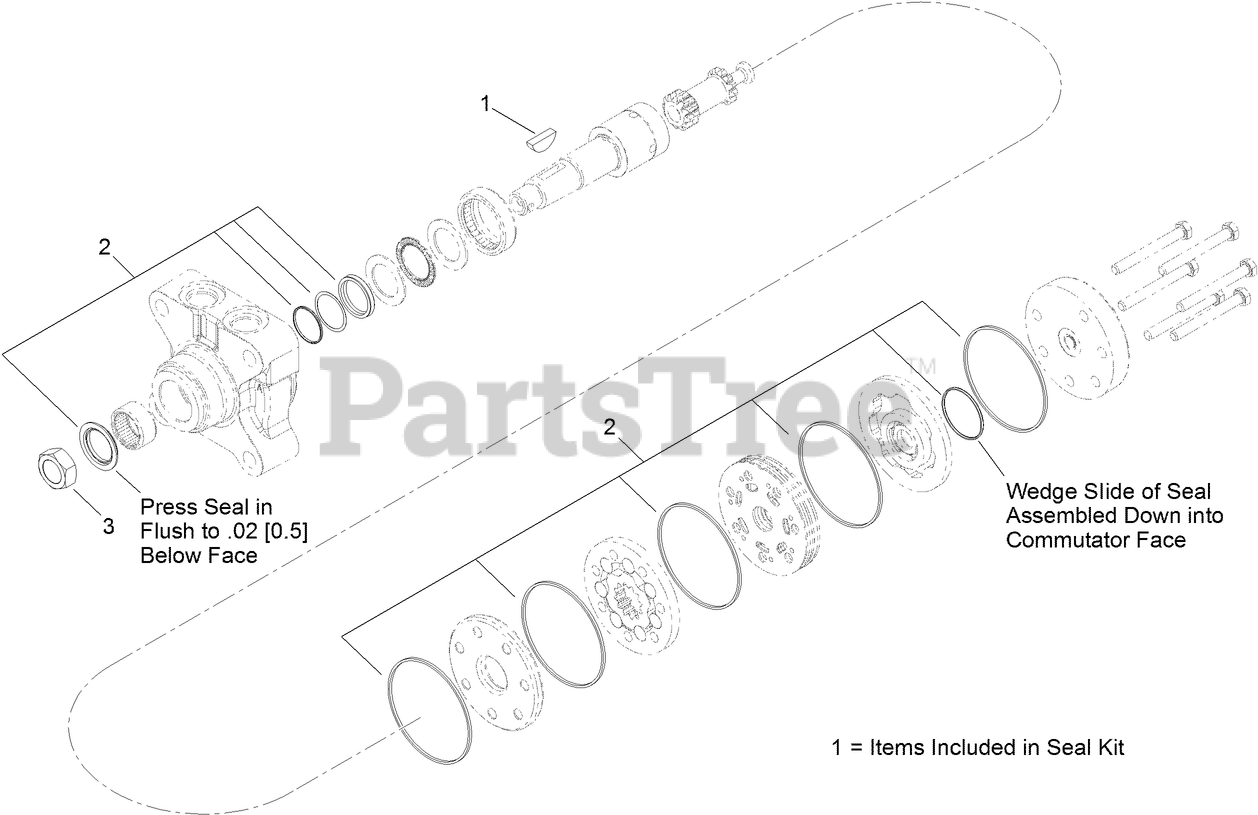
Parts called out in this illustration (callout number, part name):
1	KEY-WOODRUFF
2	SEAL KIT
3	NUT-LOCK
